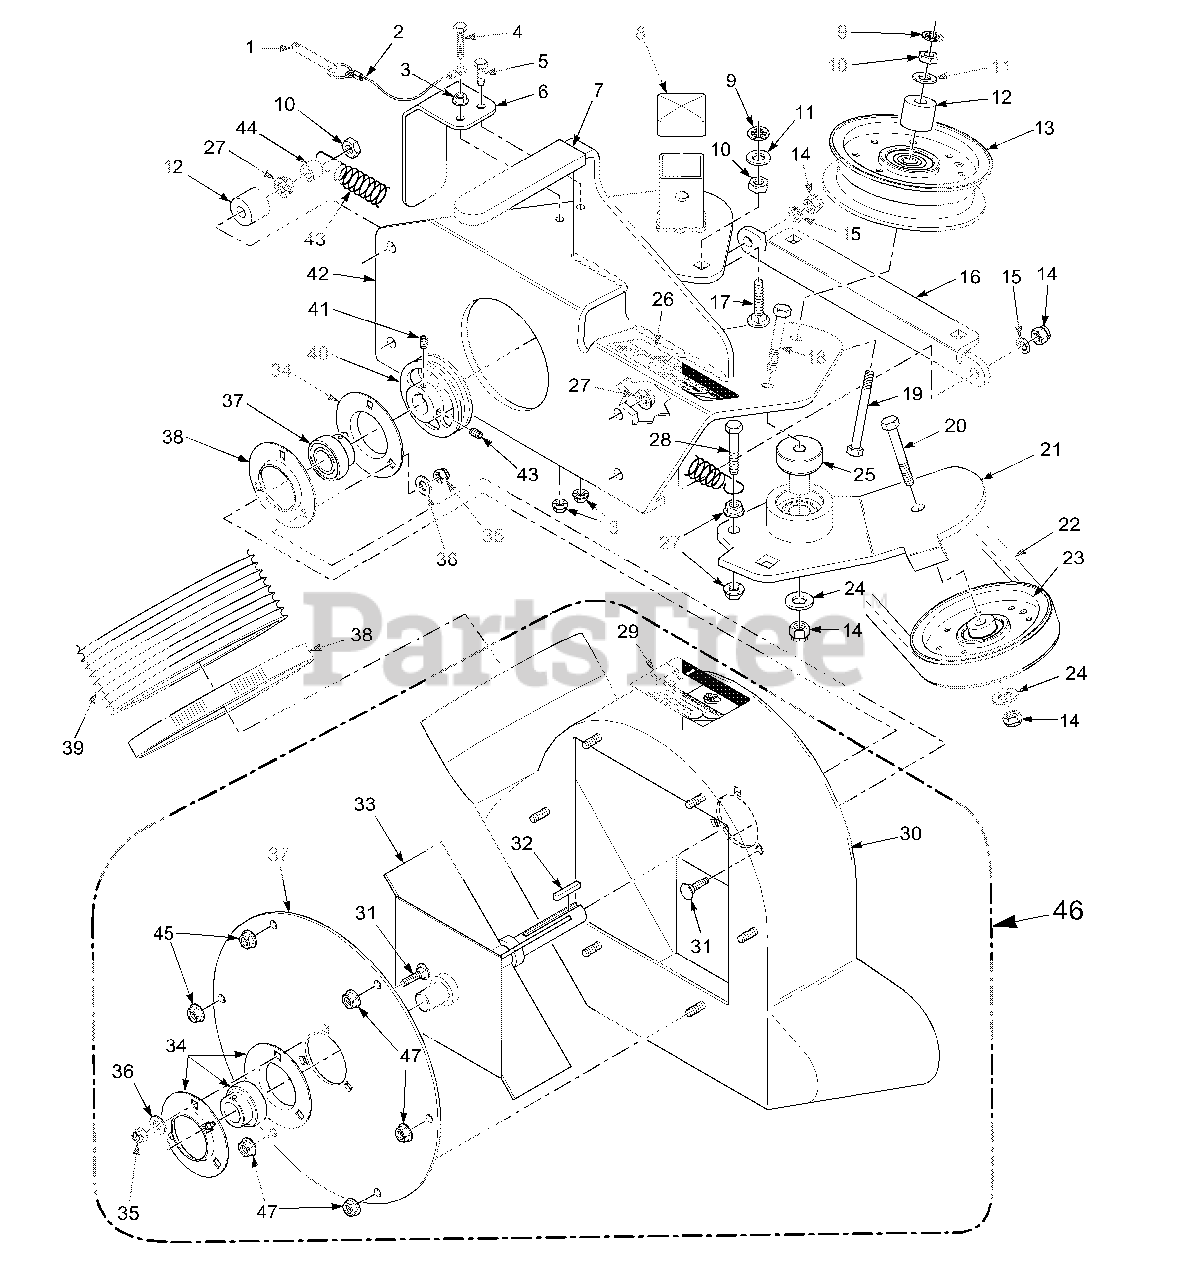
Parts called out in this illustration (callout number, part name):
1	Pin, Ring 2-1/4" Long
2	Lanyard, Deck Height Pin
3	Nut, Serr. Flange 1/4-20
4	Bolt, Hex Head 1/4-20 x 1-1/4"
5	Bolt, Hex Head 1/4-20 x 3/4"
6	Belt Cover, Rear
7	Grip, Blower Lever
8	Cap, Square
9	Nut, Push On 3/8 Thread
10	Lock Nut, 3/8-16
11	Flatwasher, 3/8-.391 x .938 x .105
12	Spacer
13	Pulley, Idler 4" Dia.
14	Nut, Elastic Stop 3/8-16
15	Lockwasher, 3/8-16
16	Plate, Catch Mounting
17	Bolt, Carr. 3/8-16 x 1-1/2"
18	Bolt, Hex Head 3/8-16 x 2-1/4"
19	Bolt, Hex Head 3/8-16 x 3-1/4"
20	Bolt, Hex Head 3/8-16 x 2"
21	Idler Arm Weldment
22	Belt, GC-STC
23	Pulley, 4" O.D.
24	Washer, 3/8 Hardened
25	Pivot, Idler
26	Decal, Belt Cover
27	Nut, Serr. Flange 3/8-16
28	Bolt, Hex Head 3/8-16 x 1-1/2 Gr. 8
29	Decal, Danger
30	Blower Housing Weldment
31	Bolt, Carr. 5/16-18 x 3/4" Gr. 5
32	Key, 1/4 x 1/4 x 1-1/2"
33	Fan Weldment
34	Bearing with Locking Collar
35	Nut, Elastic Stop 5/16-18
36	Flatwasher, 5/16-.344 x .688 x .065
37	Cover, Blower Housing
38	Clamp, 6-1/2" Max Dia.
39	Hose, 6" Dia.
40	Pulley, 4-3/4" O.D. - 1" Bore
41	Set Screw, 5/16-18 x 3/8"
42	Frame Weldment, Blower Mount
43	Spring, Main Drive
44	Spacer
45	Nut, Serr. Flange 5/16-18
46	Blower Housing Assembly
